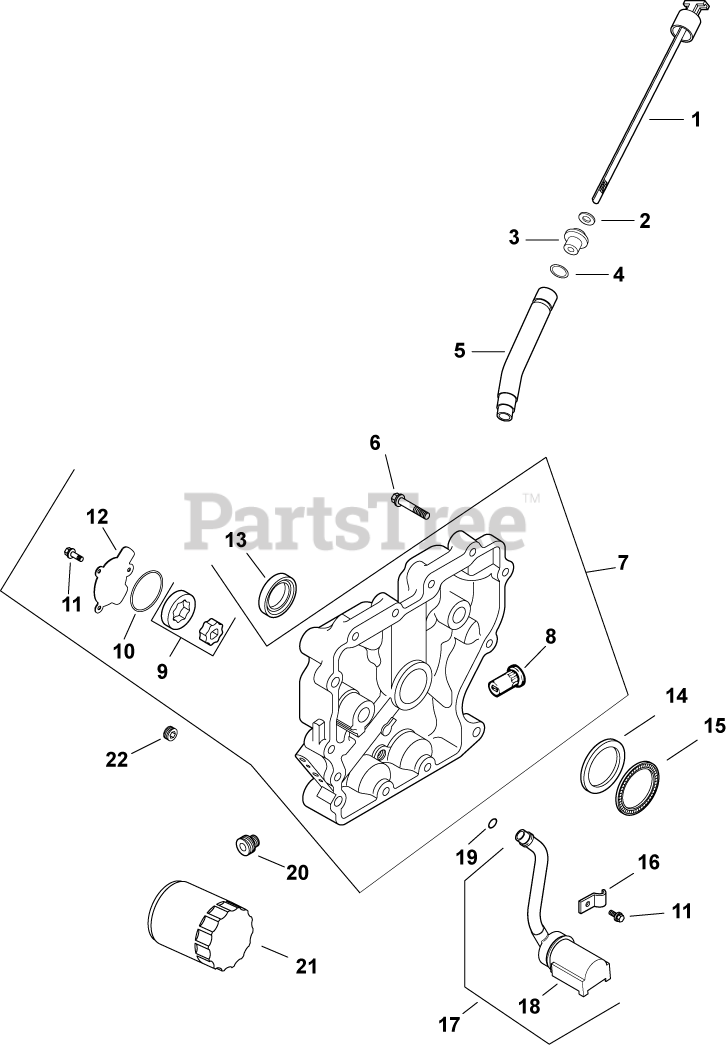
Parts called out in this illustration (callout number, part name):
3	SEAL USE 25 032 13-S
5	TUBE, OIL FILL
6	SCREW, FLG M8X1.25X45
7	CLOSURE PLATE ASSEMBLY - DISCONTINUED
8	VALVE, OIL PRESSURE RELIEF
9	PUMP ASSEMBLY, OIL
10	O-RING (1.78" DIA)
11	SCREW,FLG THD FRM M5X0.8X16-(#25086398S)
12	COVER, OIL PUMP
13	SEAL, OIL
14	WASHER, THRUST (1MM)
15	BEARING, THRUST
17	KIT, OIL PICK-UP
18	PICK-UP, OIL SCREEN
19	O-RING (.5" DIA)
20	NIPPLE, OIL FILTER
21	OIL FILTER
22	PLUG, CTSK PIPE 1/8"
